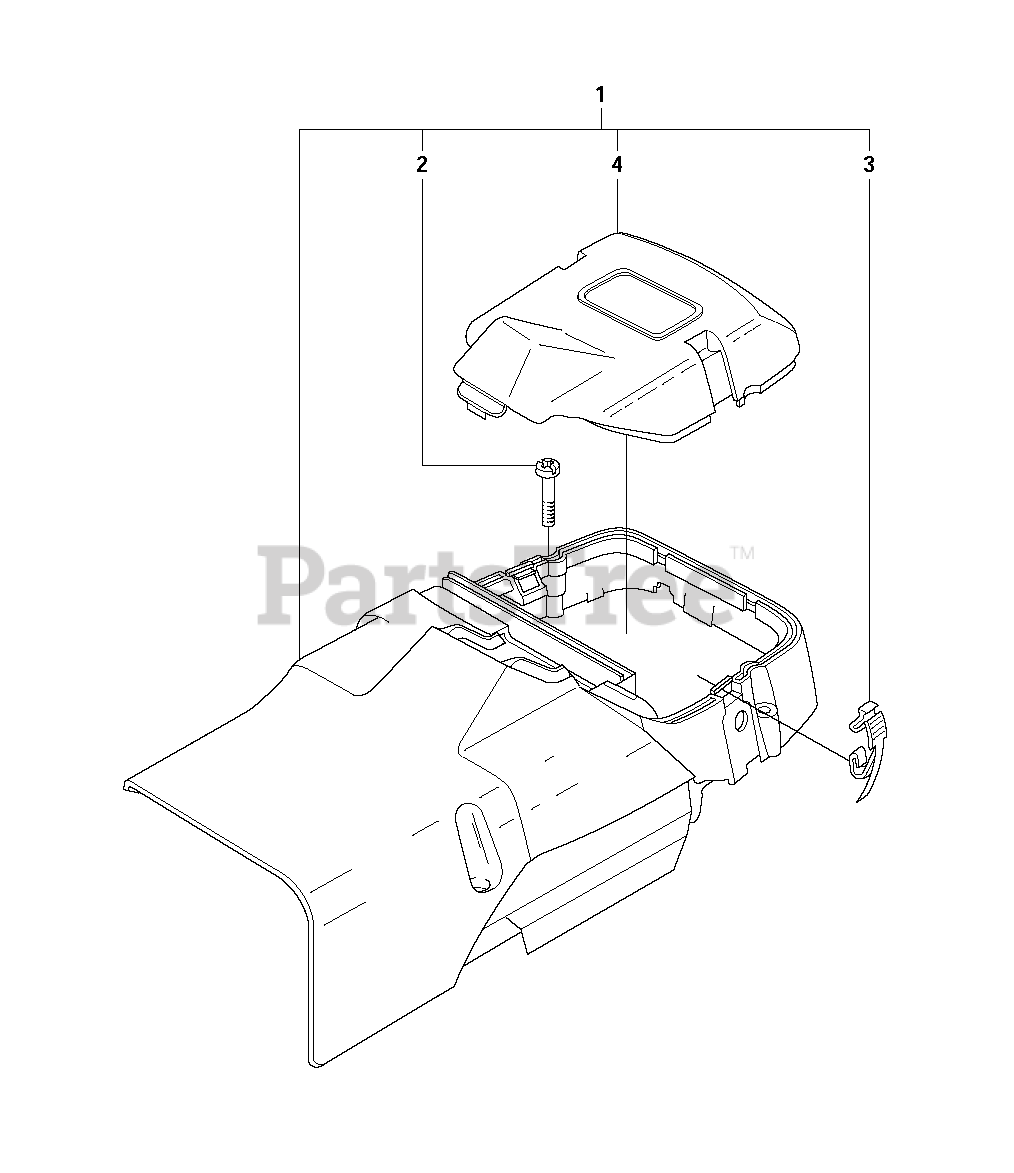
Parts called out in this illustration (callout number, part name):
1	CYLINDER COVER ASSY
2	SCREW
3	CLIP
4	FILTERCOVER
